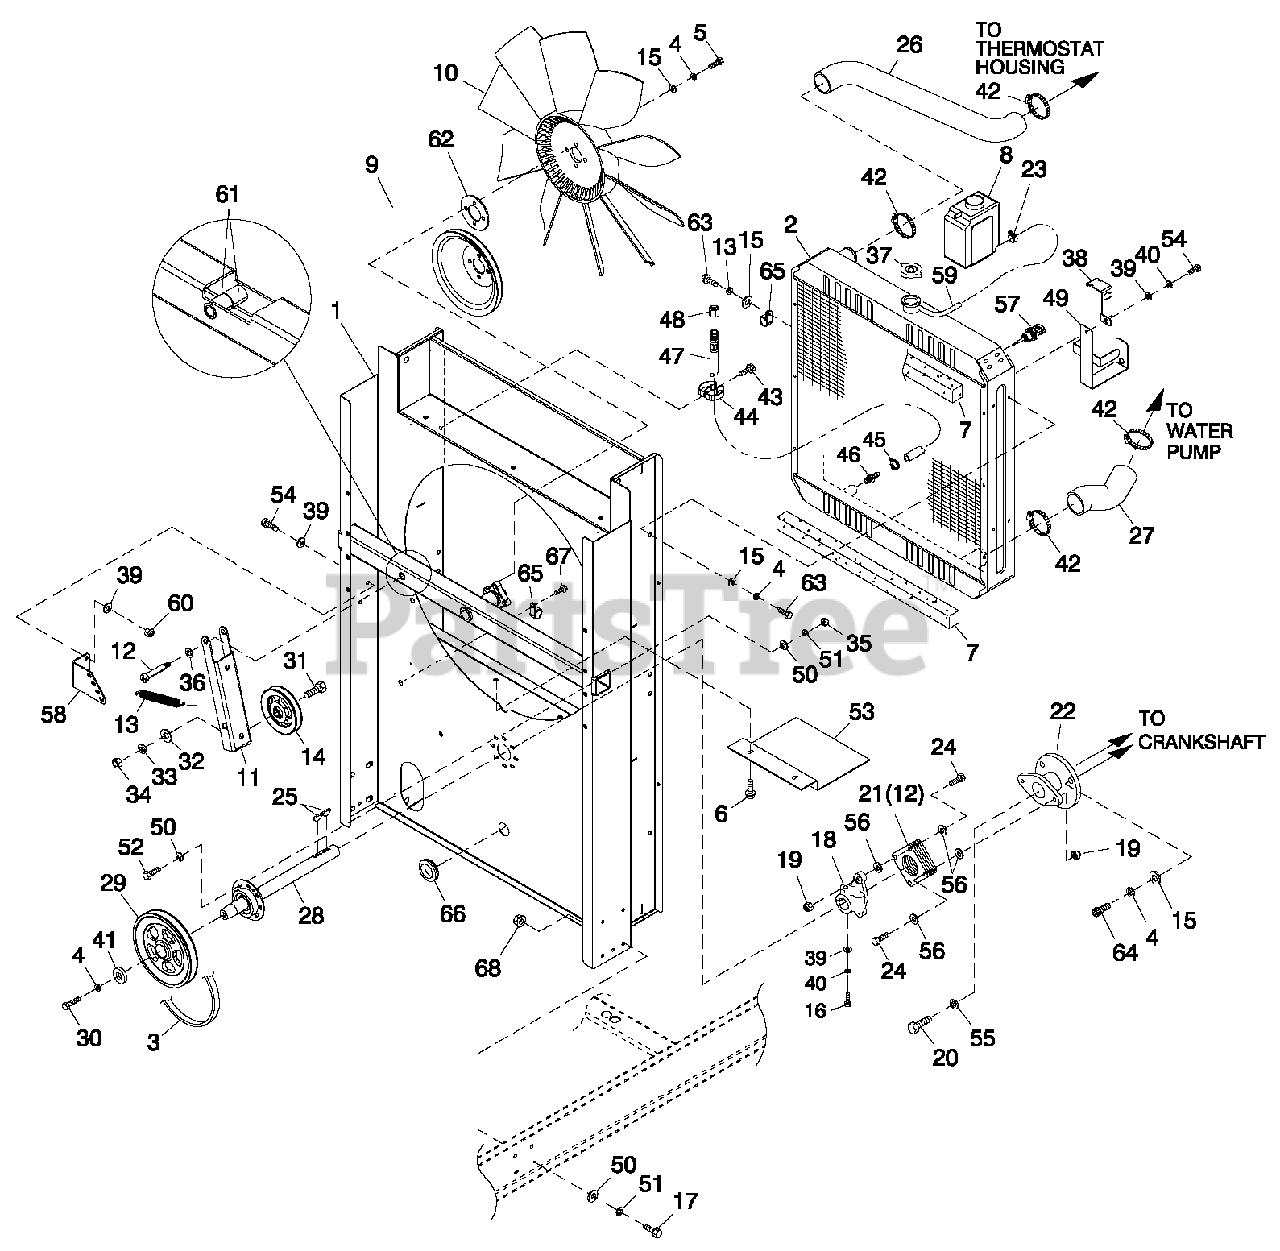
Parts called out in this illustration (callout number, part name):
1	WELDMENT RADIATOR SUPPORT C5
2	RADIATOR 680 X 680 X 70 CPL
3	V-BELT 31/64" X 62-3/8"
4	WASHER LOCK M10
5	SCREW HHC M10-1.5X30C10.9
6	SCREW THF M6-1 X 16 N WA Z/JS
7	TAPE FOAM 1 X 1 (26.75" LG)
8	TANK COOLANT RECOVERY
9	PULLEY FAN V-GROOVE 9"
10	FAN 26" LH ROTATION
11	ARM BELT TENSIONER
12	SHOULDER BOLT 1/2 X 2-1/4"
13	SPRING TENSION CPL
14	PULLEY V-BELT 4" FLANGED
15	WASHER FLAT 3/8-M10 ZINC
16	SCREW HHC M8-1.25X45C8.8
17	SCREW HHFC M6-1.0X20 G8.8
18	HUB FLEX PLATE
19	NUT HEX LOCK 5/16-24 NY INS
20	SCREW HHC M12-1.5X60G8.8
21	DISK FLEX
22	COUPLING HUB FLEX (MACH)
23	CLAMP HOSE BAND 1/4
24	SCREW HHC 5/16-24X1.124
25	KEY WOODRUFF 4X 1 9D
26	HOSE RADIATOR UPPER CPL
27	HOSE LOWER RAD CPL C5 6.8L
28	ASSY BRG/SHAFT CPL FANDRIVE
29	PULLEY 6.5" DIA MACHINED (6.8L 100KW)
30	SCREW HHC M10-1.5X30G8.8
31	SCREW HHC 1/2-13X 2" G8
32	WASHER FLAT 1/2 ZINC
33	WASHER LOCK 1/2
34	NUT HEX 1/2-13 STEEL
35	NUT HEX M 6X 1.0 G8YEL CHR
36	WASHER NYLON .50 X .87 X .06
37	CAP RADIATOR 13 PSI
38	BRACKET, SIGNAL CONDITIONER
39	WASHER FLAT 5/16-M8 ZINC
40	WASHER LOCK M8-5/16
41	SPACER .5 X 1.5 X .25 STL/ZINC
42	CLAMP HOSE #28 1.32-2.25
43	SCREW HHTT M 4 -0 .7X 8B P
44	SPRING CLIP HOLDER .37-.62
45	CLAMP HOSE .38-.87
46	BARBED STR 3/8 N PTX3/8
47	HOSE DRAIN ASSY 28"
48	CAP HEX 1/4 NPT BRASS
49	BRACKET COOLANT TANK
50	WASHER FLAT 1/4-M6 ZINC
51	WASHER LOCK M6-1/4
52	SCREW HHC M 6-1.0X 20G 8.8
53	SHIELD RADIATOR
54	SCREW HHC M8-1.25X20G8.8
55	WASHER LOCK M12
56	WASHER FLEX (THIN)
57	PROBE COOLANT LEVEL 3/8-18NPTF
58	BRACKET TENSIONER SPRING
59	HOSE 9/32 ID (43"LG)
60	NUT HEX LOCK M8-1.25 NY INS
61	BEARING SLEEVE 1/2/ X 3/4 X 1
62	SPACER CPL COOLING FAN 1/8"
63	SCREW HHC M10-1.5X20C8.8
64	SCREW SHC M10-1.5X 35 G12.9
65	CLAMP STL/VNL.62 X .406 Z
66	GROMMET 1.37 X .06 X 1.00
67	SCREW HHTT M6-1.0X16ZYC
68	NUT FLANGE M6-1.0 NYLOK
